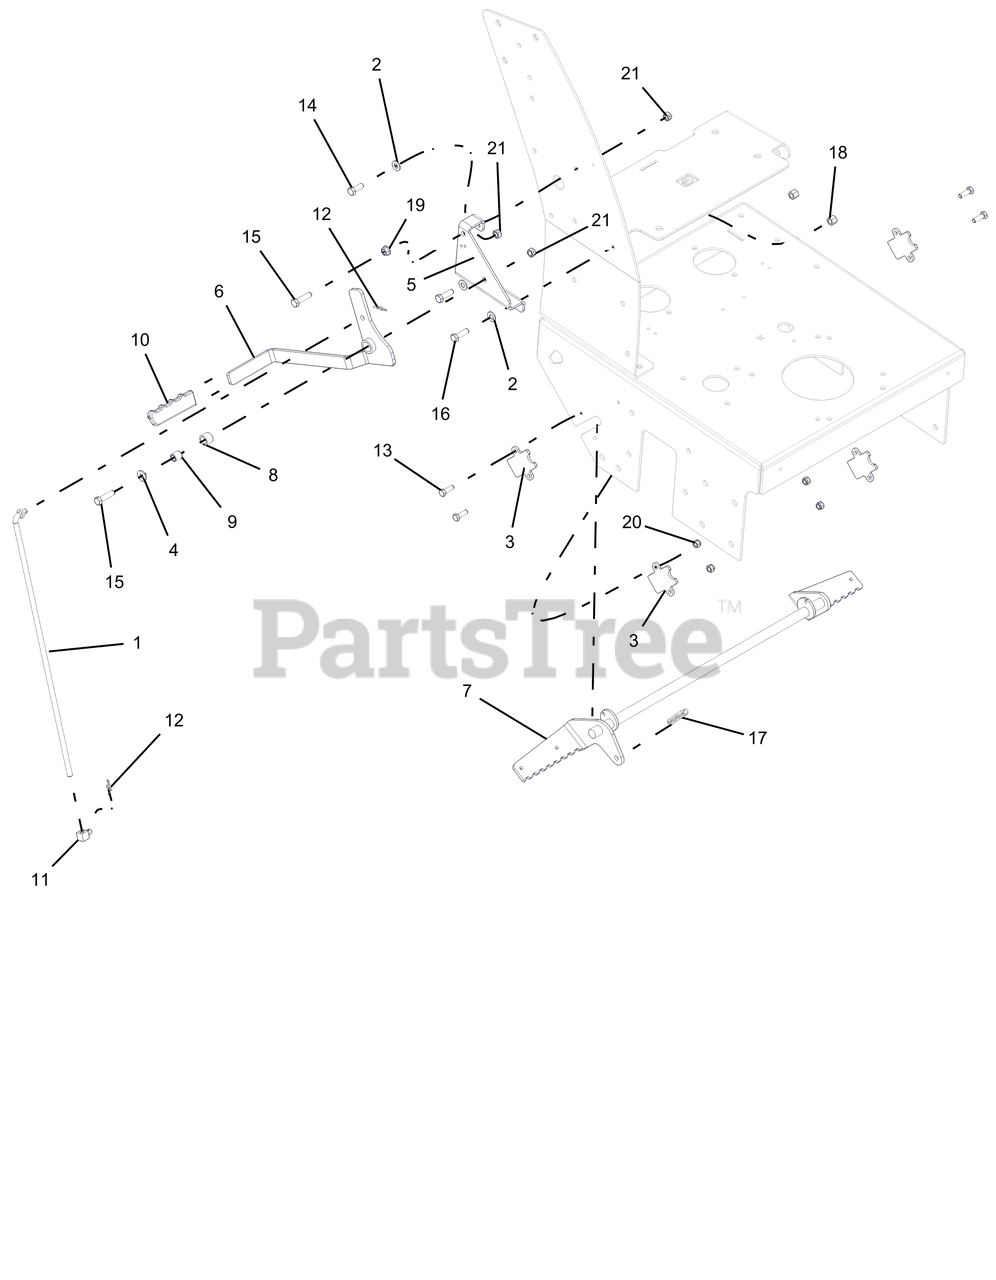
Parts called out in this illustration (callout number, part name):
1	ROD, DRIVE CONTROL FW
2	WSHR-FL-STL.406X.812X.065 YWZ
3	SHOE, BRAKE SYSTEM FLOAT WALK-RED
4	WSHR-FL-STL.38X.875X.083 YWZC
5	LOCATOR, BRAKE ARM WD-RED
6	HANDLE, PARK BRAKE
7	WLDMT, BRAKE SYS FLOAT HYDRO-BLACK
8	PARK BRAKE HANDLE BUSHING
9	PARK, BRAKE LEVER SPACER
10	GRIP
11	SWIVEL, 3/8-24
12	RING, RUE .375 x .054 x 1.254
13	BLT-HEX .31-18X1.00 GR5 YWZC
14	BLT-HEX .38-16X1.00 GR5 YWZC
15	BLT-HEX .38-16X1.50 GR5 YWZC
16	BLT-HEX .38-16X1.25 GR5 YWZC
17	SPRG, EXTENSION
18	NUT-LK-NYL .38-16 YWZC
19	@NUT-SPNLK-FLG .375-16 YWZC
20	NUT-LK-NYL .312-18 YWZC
21	NUT-LK-CTR .38-16 YWZC
